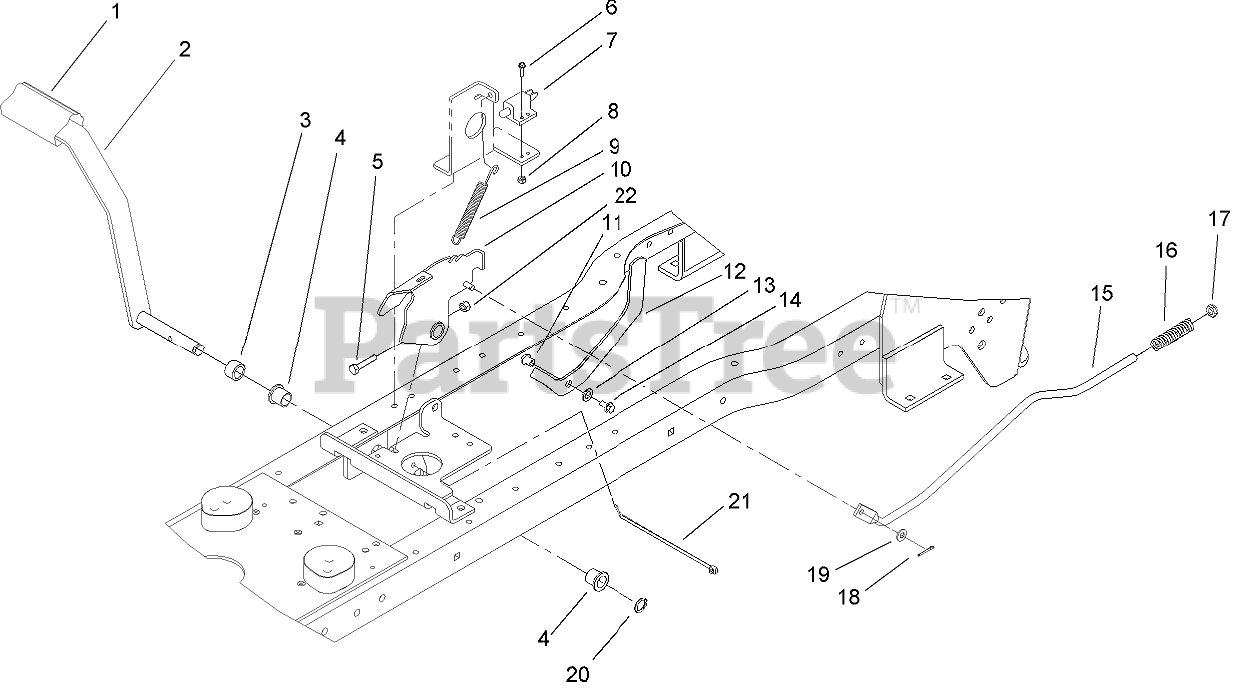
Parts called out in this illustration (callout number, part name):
1	PAD-PEDAL
2	BRAKE PEDAL ASM
3	SPACER-BRAKE
4	BUSHING-FLANGE
5	SCREW-HH
6	SCREW-SHH
7	SWITCH-POLE, SINGLE
8	NUT-LOCK
9	SPRING-EXTENSION
10	Brake ASM
11	POST-MOUNTING, LINKAGE
12	Lever-Brake, Parking
13	SPACER-BRAKE, PARKING
14	SCREW-HHF
15	ROD-BRAKE
16	SPRING-COMPRESSION
17	NUT-HEX
18	PIN-COTTER
19	WASHER-FLAT
20	RING-RETAINING
21	TIE-CABLE
22	NUT-LOCK, NI
